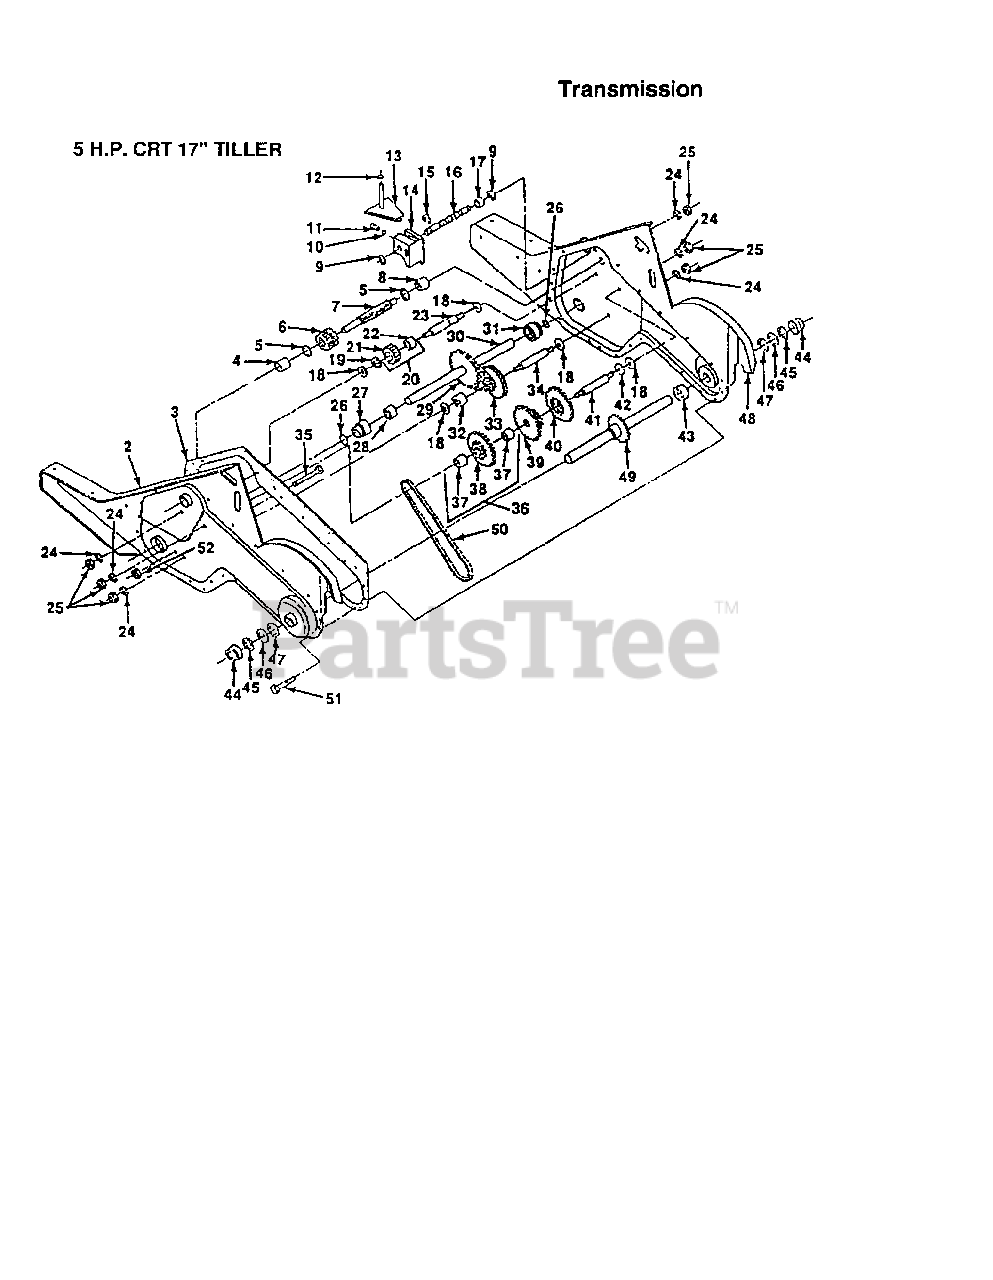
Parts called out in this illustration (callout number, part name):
3	GASKET TI
4	NEEDLE BRNG LT
5	"T, BEARING"
6	PINION-INPUT CRT
7	SHAFT-INPUT CRT
8	"TI, BEARING"
9	WASHER SEAL CRT
11	SPRING-SHIFT CRT
12	O-RING TI
13	ARM ASSY CRT
14	SHIFT FORK TI
15	KLIP RING
16	SHAFT SHIFT CRT
17	SPACER SPLIT CRT
18	WASHER
19	KLIP RING
20	GEAR ASSY CRT
21	GEAR-REV IDLR CRT
22	NEEDLE BEARING TI
23	SHAFT CRT
24	LOCKWASHER
25	NUT.ASF.HEX.7/16
26	O RING CRT
27	"CRT, BEARING"
28	BUSHING TI
29	CHAIN CRT
32	SPACER TI
33	SPRCKT 8 GEAR CRT
34	SHFT 2ND RED. CRT
35	SCRW WHIZ LOK CRT
37	BEARING
39	GEAR TI
40	GEAR TI
41	REDUCTION SHFT TI
42	BRNG RACE
43	SPACER TI
44	CUP.FORMED.
45	RING SPIRAL CRT
49	SHAFT ASSY TI
50	CHAIN.50 LINK TI
51	SCREW CRT
52	NUT.HEX.5/16-18
53	GREASE PREMIUM-1
